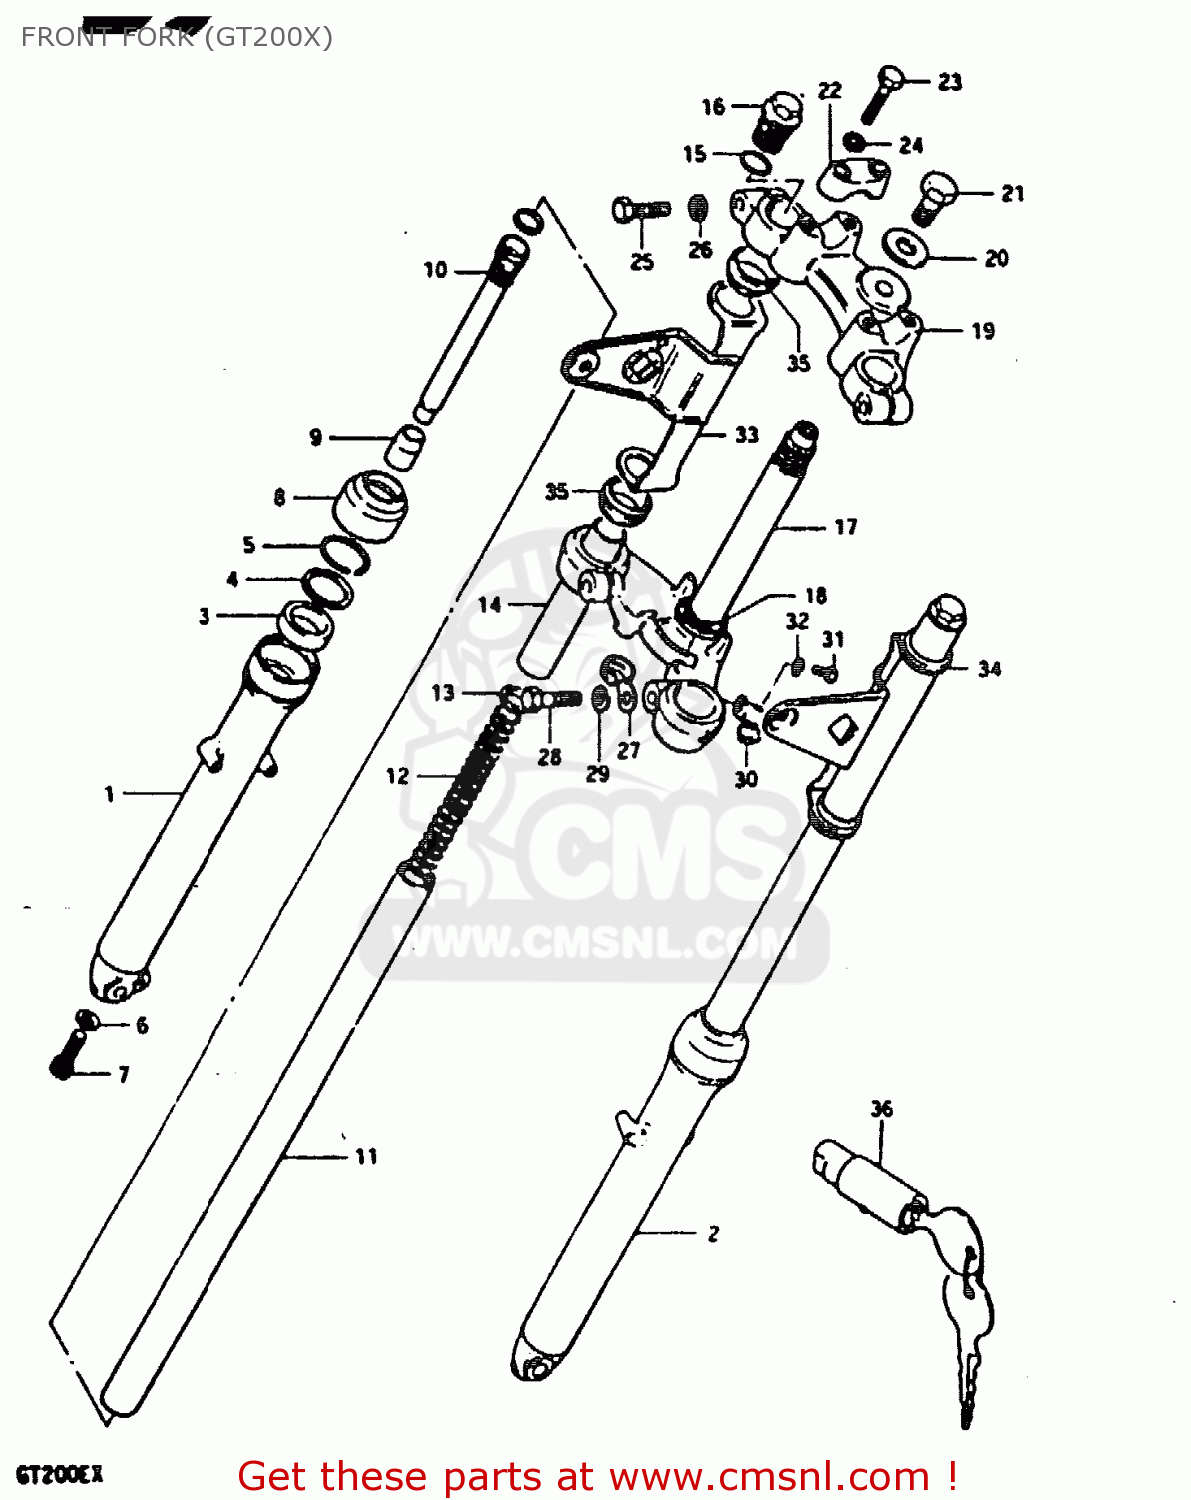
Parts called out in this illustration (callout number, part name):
1	OUTER TUBE, RH
2	OUTER TUBE, LH
3	OIL SEAL,FRONT FORK
4	WASHER,FRONT FORK
5	RING,SNAP
6	GASKET (NAS)
7	BOLT,FORK CYLINDER(10X25)
8	SEAL,DUST
9	PIECE,OIL LOCK
10	CYLINDER
11	INNER TUBE
12	SPRING
13	GUIDE,SPRING COVER
14	SPACER
15	O-RING,FORK INNER TUBE
16	BOLT,FR FORK
17	STEERING STEM
18	RACE,STEERING OUTER LWR
19	HEAD,STEERING STEM
20	WASHER,STEM HEAD(10.5X30X3.2)
21	BOLT,FORK INNER TUBE
22	HOLDER,HANDLE(BLACK)
23	BOLT
24	LOCK WASHER
25	BOLT,FORK INNER TUBE F
26	LOCK WASHER
27	CLIP
28	BOLT,FR FORK LWR(12X33)
29	WASHER,LOCK 12
30	CLIP
31	SCREW
32	LOCK WASHER
33	BRACKET, HEADLAMP RH
34	BRACKET, HEADLAMP LH
35	CUSHION
